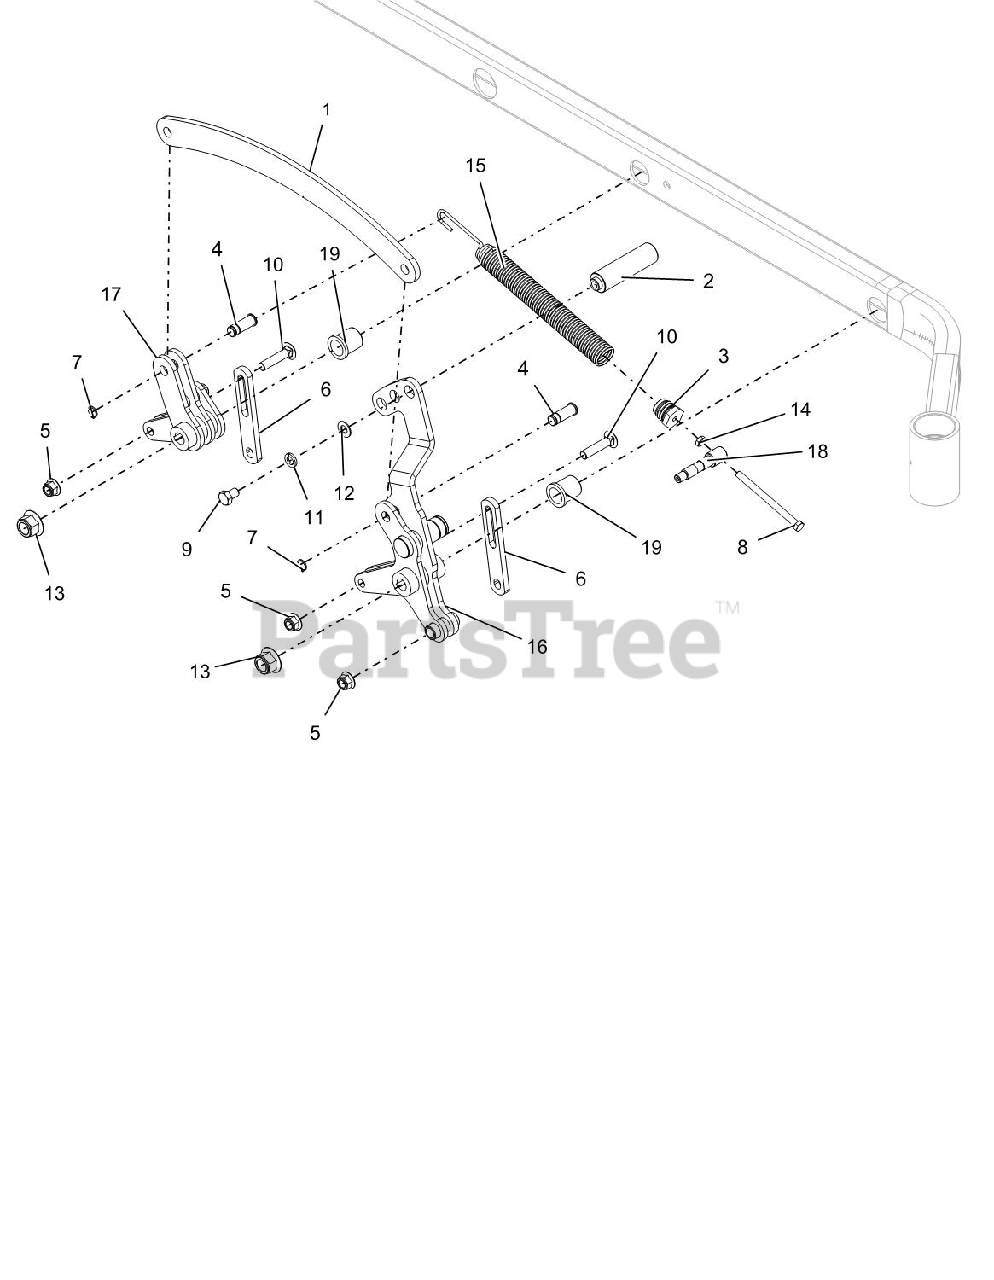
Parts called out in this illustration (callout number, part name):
1	LINK, CONNECTING
2	FOOT PEG, DECK LIFT
3	PLUG, SPRING
4	PIN, CLEVIS .625 SNAP RING
5	NUT-LK-NYL-FLG .50-13 YWZC
6	LINK-DECK LIFT - LONG
7	RG-RTNG-EXT .625X.050
8	BLT-HEX .38-16X5.00 GR5 FTH YZ
9	BLT-HEX .50-13X.75 GR5 YWZC
10	BLT-RDHDSQNK .50-13X2.25 G5YZ
11	WSHR-LK .50X.125 REG YWZC
12	WSHR-FL-STL .505X1.00X.062YWZC
13	NUT-LK-NYL-FLG .75-10 YWZC
14	NUT-HEX-JAM .375-16 YWZC
15	SPRING, DECK LIFT
16	FRONT RH DECK LIFT ARM WMT -LF
17	REAR RH DECK LIFT ARM WMT -LF
18	TRUNION, DECK LIFT SPRING
19	BSHG-FLG 1.00X1.25X1.50X1.50
